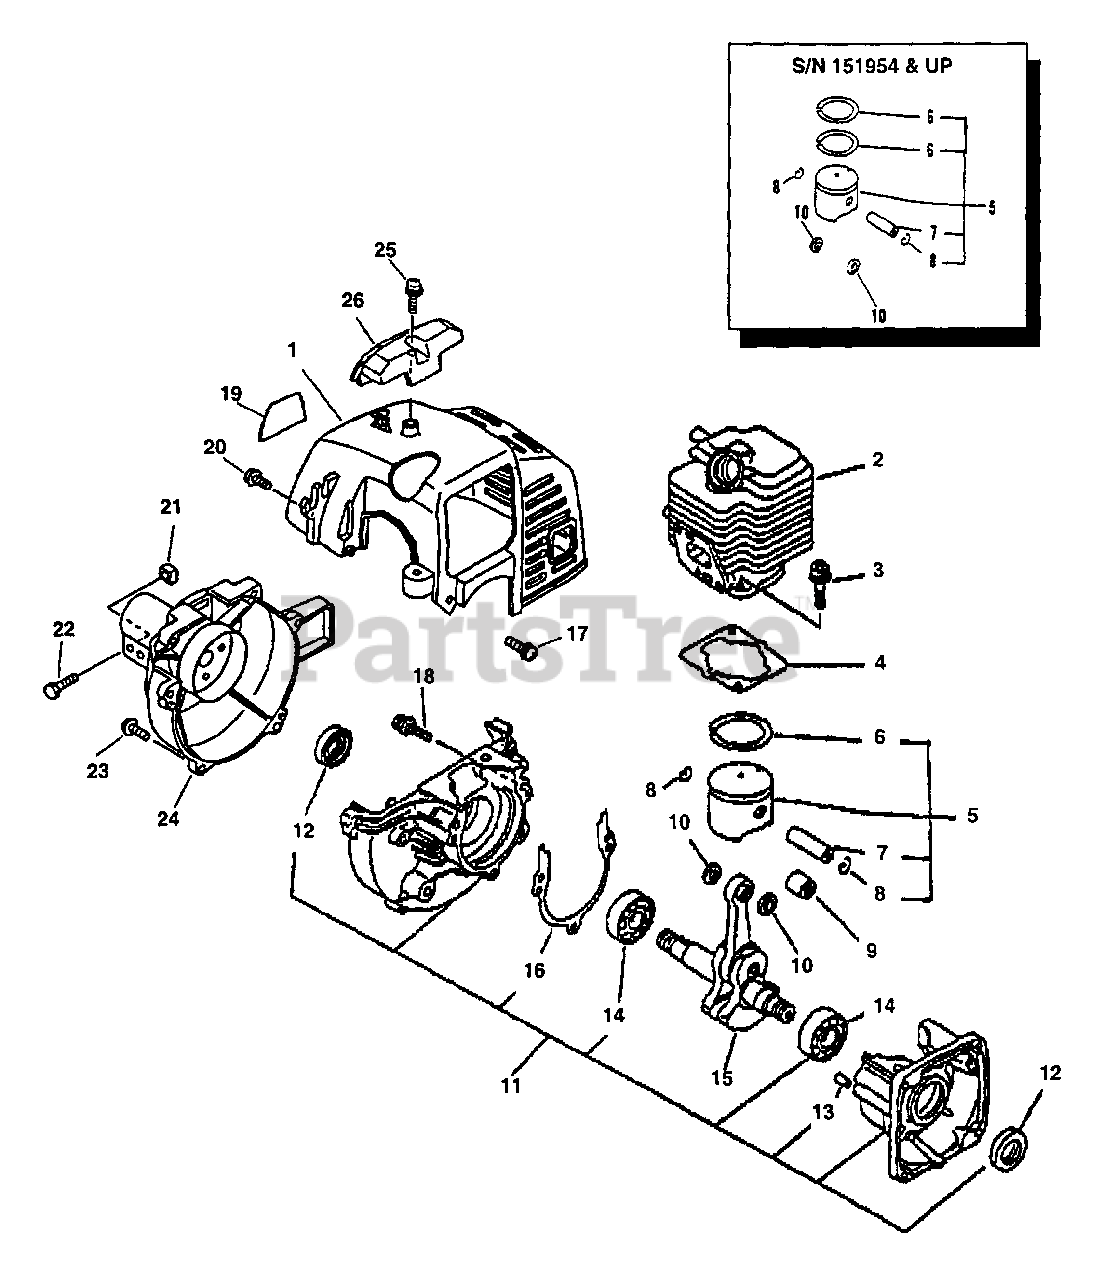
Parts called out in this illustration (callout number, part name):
1	COVER, ENGINE - GRAY
2	CYLINDER
3	SCREW - 5X22
4	GASKET, CYLINDER
5	PISTON KIT
6	RING, PISTON
7	PIN, PISTON
8	RING, RETAINING
9	BEARING, NEEDLE
10	SPACER, PISTON
11	CRANKCASE KIT
12	SEAL, OIL
13	PIN - LOCATING
14	BEARING, BALL - 6201
15	CRANKSHAFT ASSY
16	GASKET, CRANKCASE
17	SCREW - 4X12 -- TAPPING
18	SCREW - 5X28
19	LABEL - MODEL GT-2000
20	SCREW - 4X16
21	NUT - 5 -- SQUARE
22	BOLT - 5X28
23	SCREW - 4X18
24	FAN CASE ASSY
25	SCREW - 5X16 -- TAPPING
26	GUARD, TOP - GRAY
